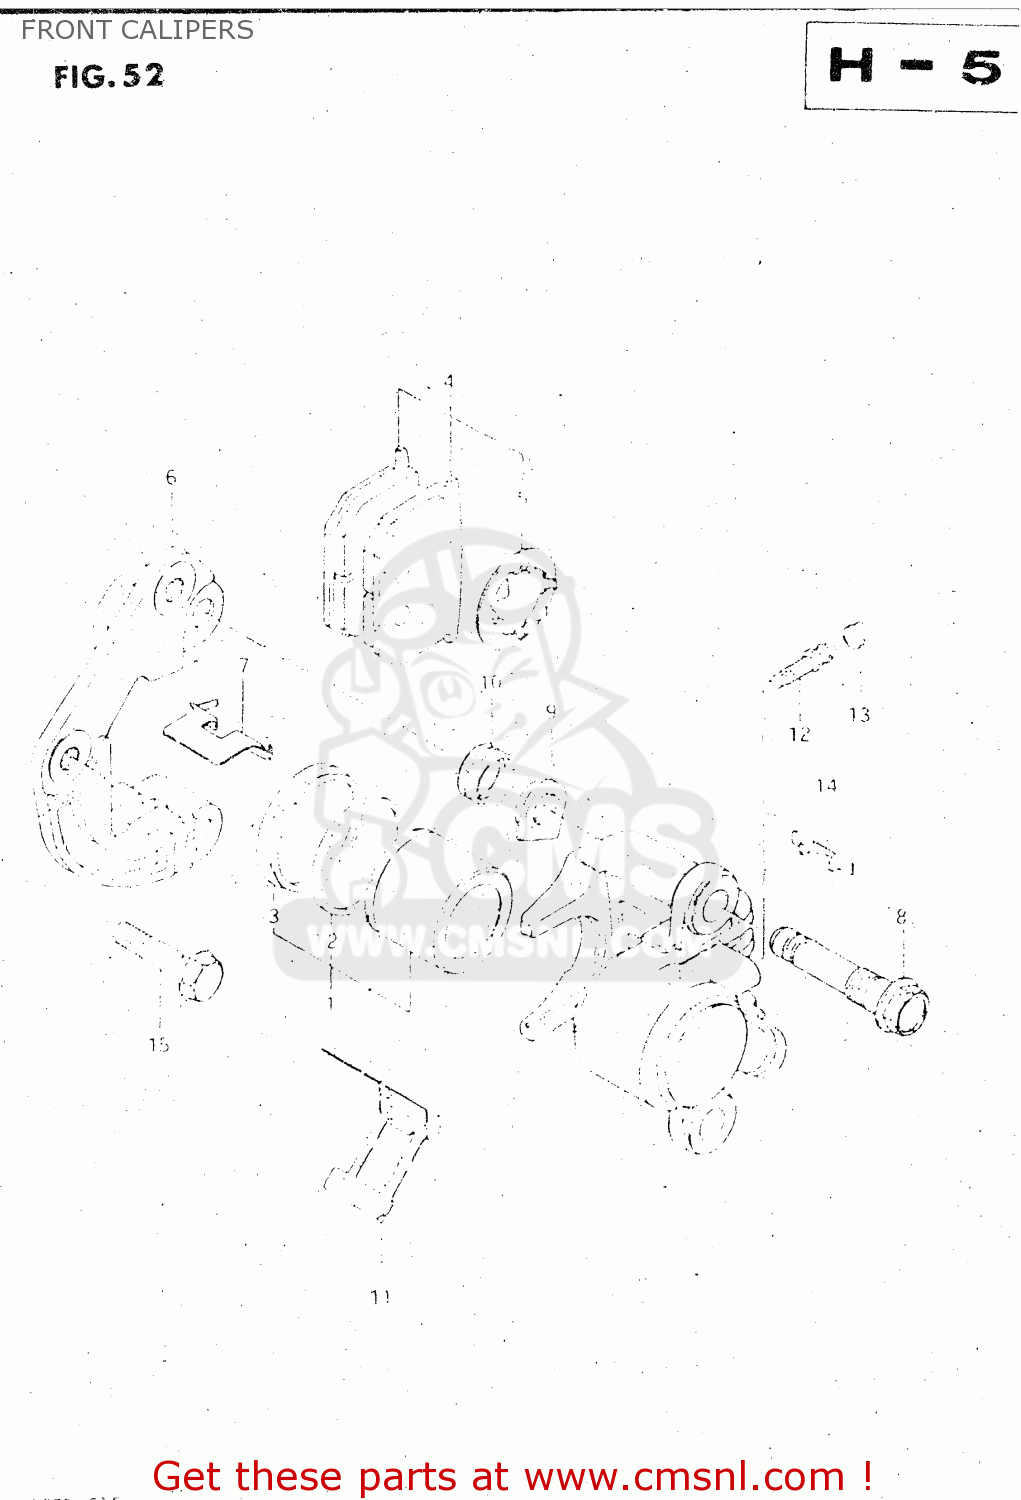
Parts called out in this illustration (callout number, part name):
1	PISTON SET
2	SEAL,PISTON
3	BOOT,PISTON
4	PAD & SHIM SET (MCA)
5	SHIM,PAD
6	HOLDER,CALIPER,LEFT
7	PAD,GUIDE
8	AXLE,CALIPER
9	NUT,CALIPER AXLE
10	BOOT
11	SPRING
12	BREATHER
13	CAP,BLEEDER PL
14	COVER,INDICATOR
15	BOLT 10X37
